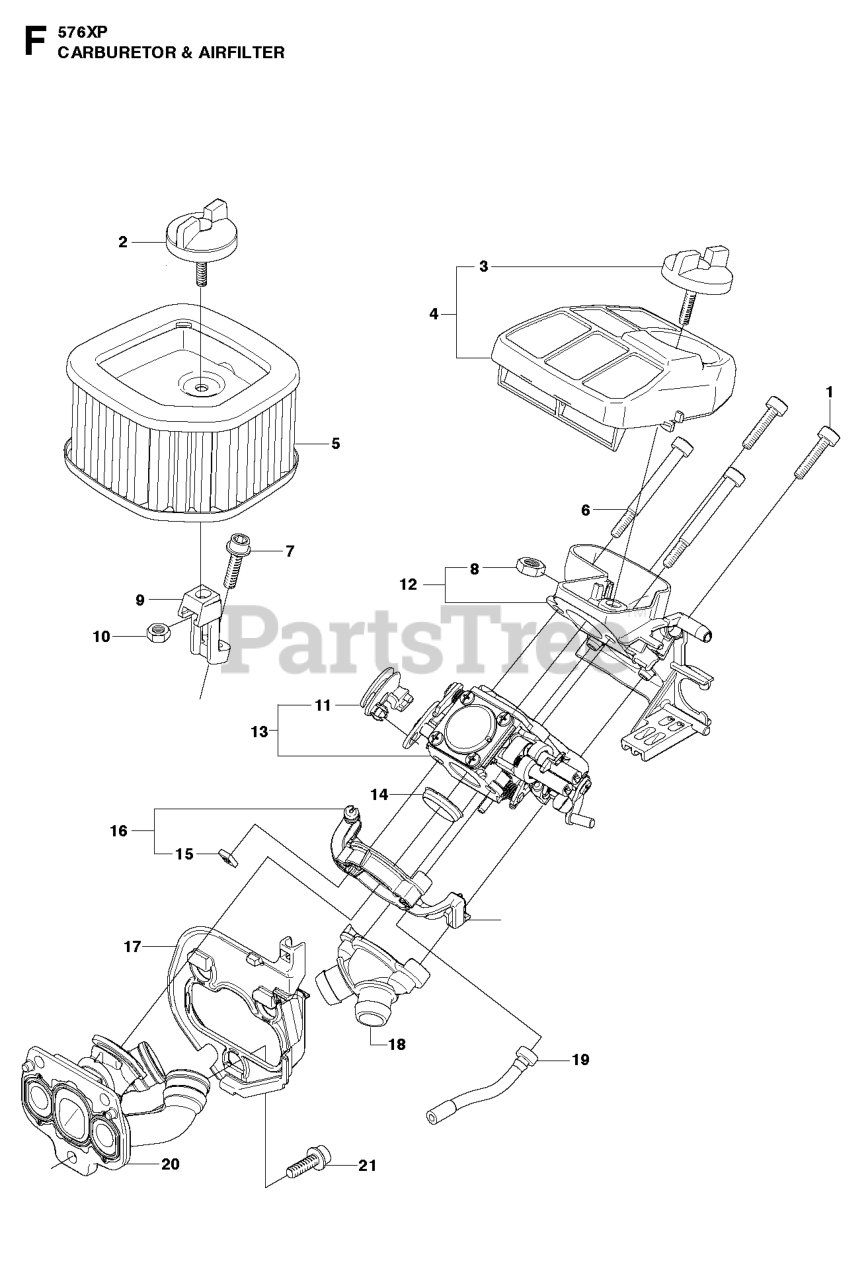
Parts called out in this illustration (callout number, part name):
3	KNOB
4	RP AIR FILTER
4	AIR FILTER
5	AIR FILTER
5	AIR FILTER WINTER
5	AIR FILTER HD 44
6	SCREW 4X46
8	NUT
10	NUT
11	LEVER
12	FILTER HOLDER
13	RP CARBURETOR
15	NUT
